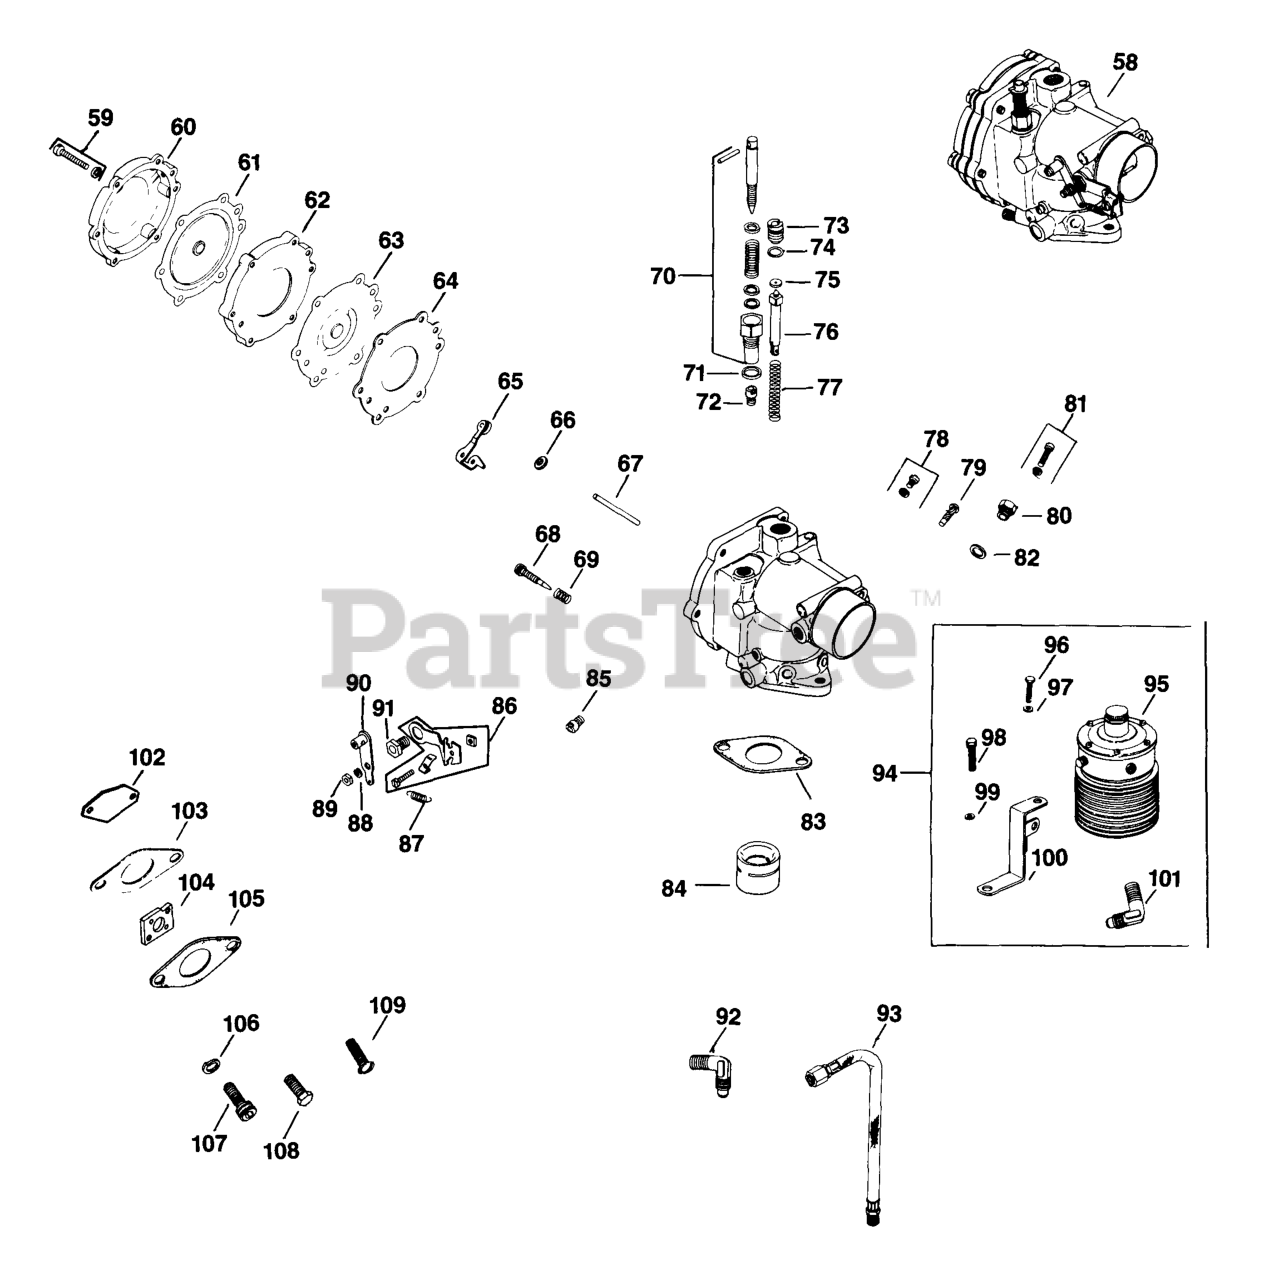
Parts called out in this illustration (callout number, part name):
58	CARBURETOR - DISCONTINUED
59	Screw, #10-32
60	Cover, diaphragm
61	DIAPHRAGM - DISCONTINUED
63	KIT - USE 277896
64	KIT - USE 277896
65	Lever, diaphragm
66	WASHER - DISCONTINUED
67	KIT - USE 277896
68	KIT - USE 277896
69	KIT - USE 277896
70	JET - DISCONTINUED
71	KIT - USE 277896
72	Jet, main
76	VALVE - DISCONTINUED
77	SPRING - DISCONTINUED
78	PLUG - DISCONTINUED
79	KIT - USE 277896
80	PLUG - DISCONTINUED
81	SCREW - DISCONTINUED
83	GASKET - DISCONTINUED
84	Venturi
85	SCREW - DISCONTINUED
86	BRACKET - DISCONTINUED
87	SPRING - DISCONTINUED
88	WASHER, SPRING LOCK #10
89	NUT - DISCONTINUED
90	LEVER - DISCONTINUED
93	LINE - DISCONTINUED
94	VAPORIZER - DISCONTINUED
95	VAPORIZER
96	SCREW - DISCONTINUED
98	SCREW,CAP HD 3/8-16x1/2"
99	WASHER, INT TOOTH LOCK 3/8"
100	BRACKET - DISCONTINUED
102	PLATE - DISCONTINUED
103	SPACER - DISCONTINUED
104	ADAPTER - DISCONTINUED
105	GASKET - DISCONTINUED
106	WASHER, SPRING LOCK 5/16"
106	WASHER, INT TOOTH LOCK 5/16"
107	SCREW, HEX SOCKET HEAD CAP USE 25 086 87-S
108	SCREW,CAP HD 5/16-24x5/8"
109	SCREW - DISCONTINUED
277896-S	KIT, CARBURETOR REPAIR - DISC.
